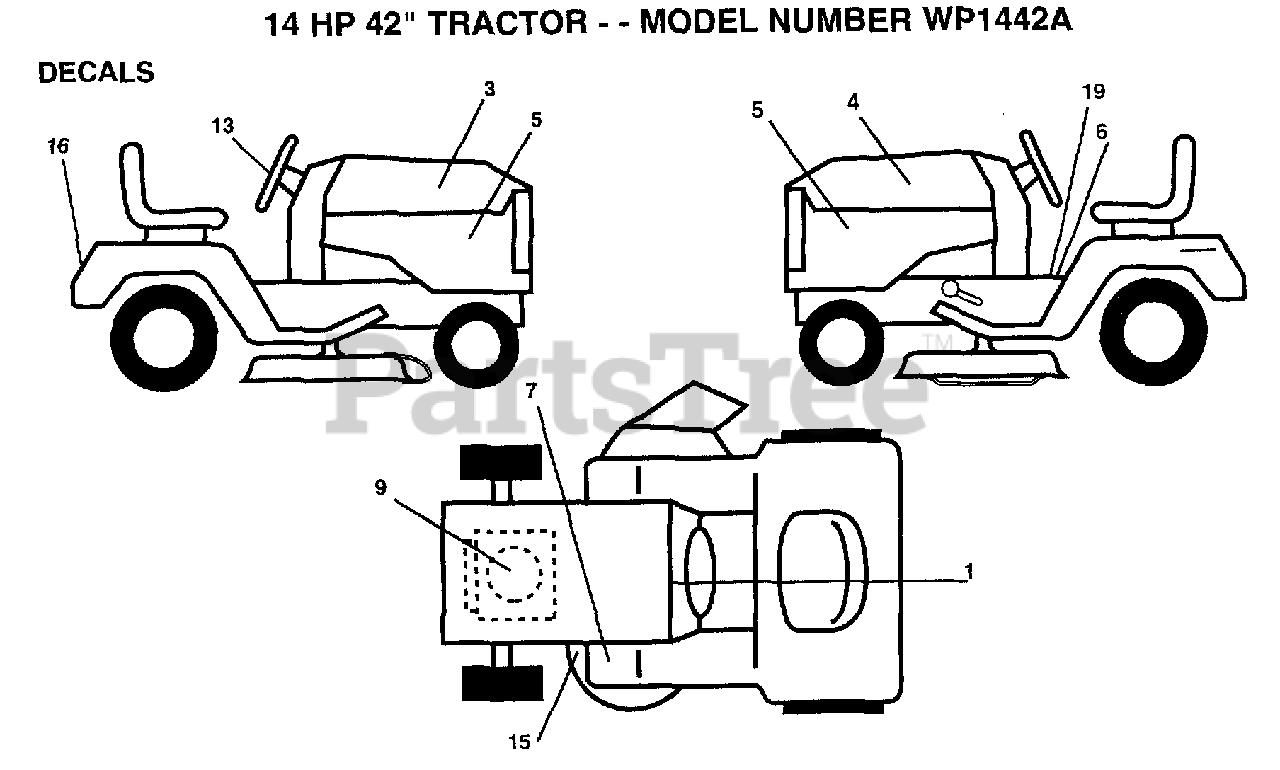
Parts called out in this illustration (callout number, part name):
1	DECAL.DASH.INST.
3	DECAL.HOOD.RH
4	DECAL.HOOD.LH
6	DECAL
9	DECAL.ENG.272750
11	"DECAL, WARNING"
13	DECAL, INSERT
15	DECAL.V.BELT
16	DECAL, FENDER LOGO
19	DECAL BRAK PARK
